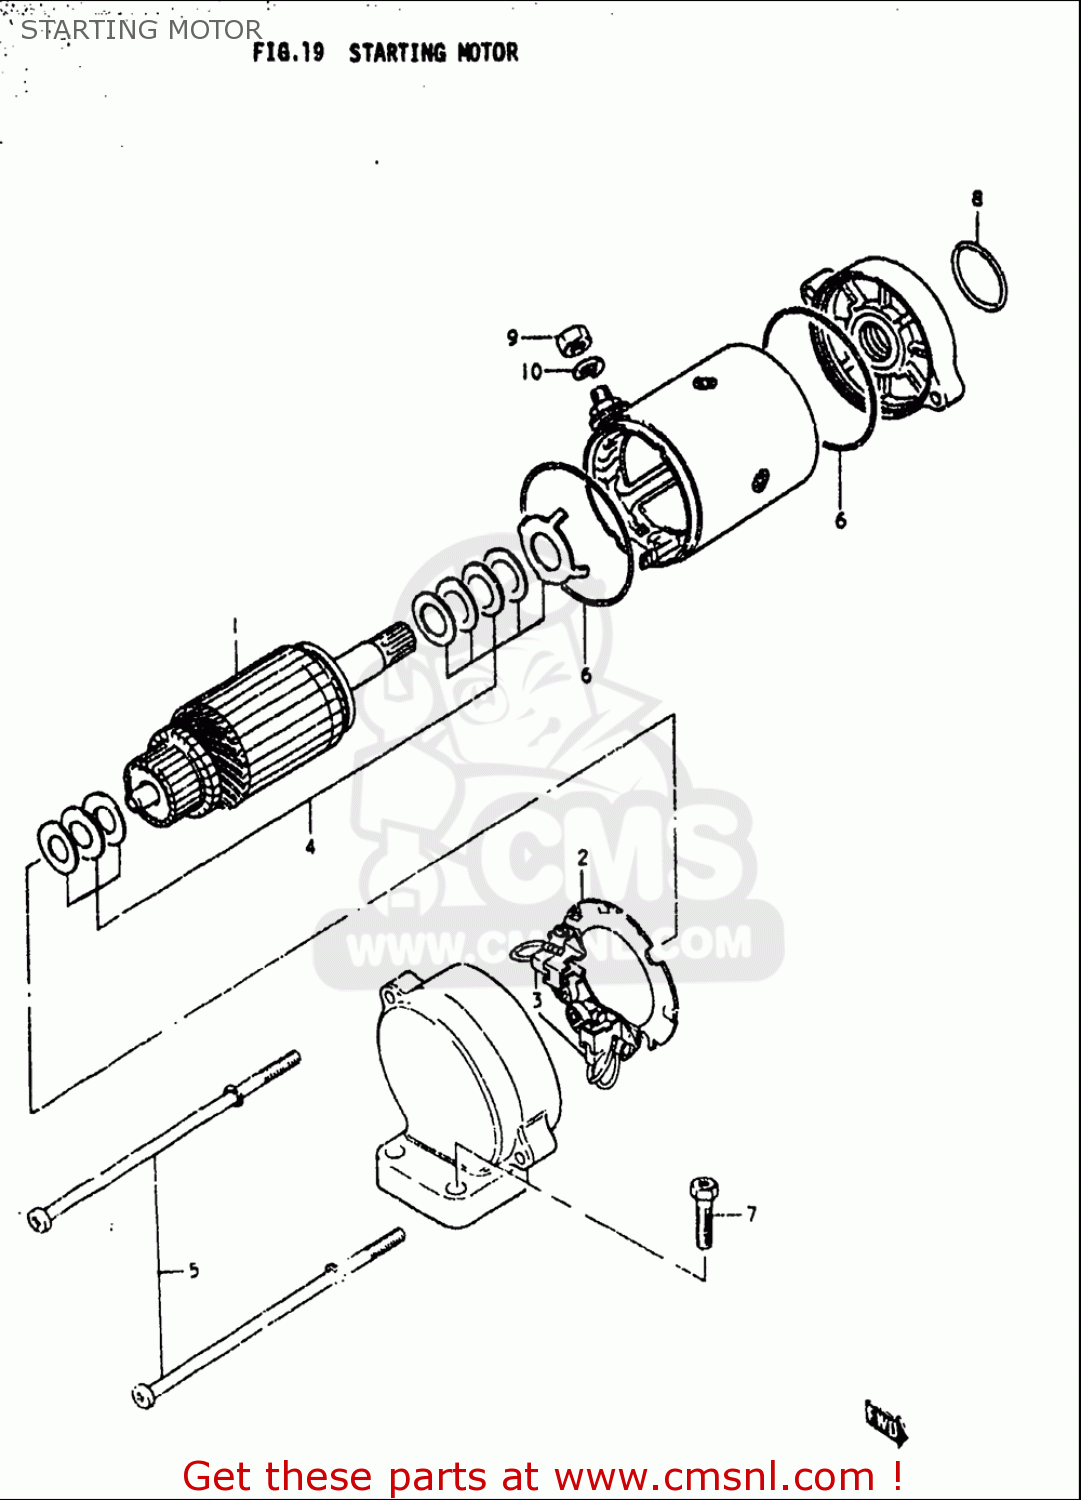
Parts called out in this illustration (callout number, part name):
2	HOLDER ASSY
3	BRUSH SET
5	BOLT
6	O RING
7	SCREW (6X25)
8	O RING(D:2,ID:24.5)
9	NUT
10	WASHER,LOCK
